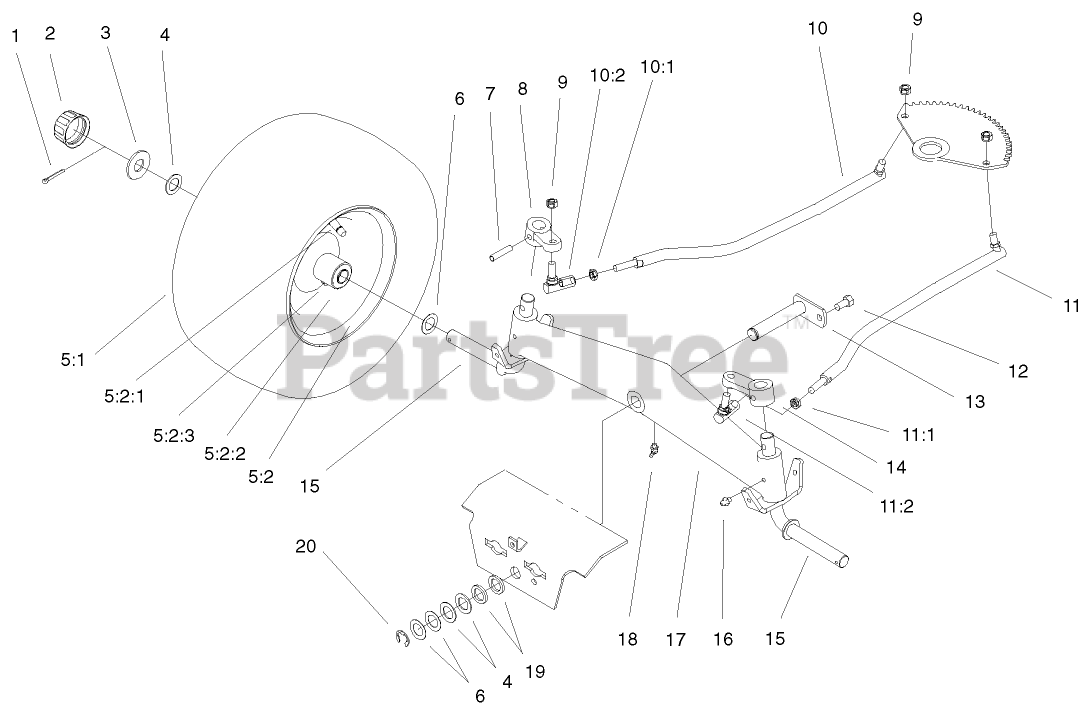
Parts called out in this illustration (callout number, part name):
1	PIN-COTTER
2	CAP-HUB
3	WASHER-PLAIN
4	WASHER
5:2	WHEEL ASM
5:2:1	VALVE
5:2:2	BEARING-WHEEL
5:2:3	ZERK-GREASE
6	WASHER-SHIM
10	LINKAGE-STEERING, RH
11	LINKAGE-STEERING, LH
12	SCREW-HWH, TAPTITE
13	PIN-AXLE
16	FITTING-GREASE
17	AXLE ASM-FRONT
18	FITTING-LUBE, 45 DEG
19	WASHER
20	E-RING
